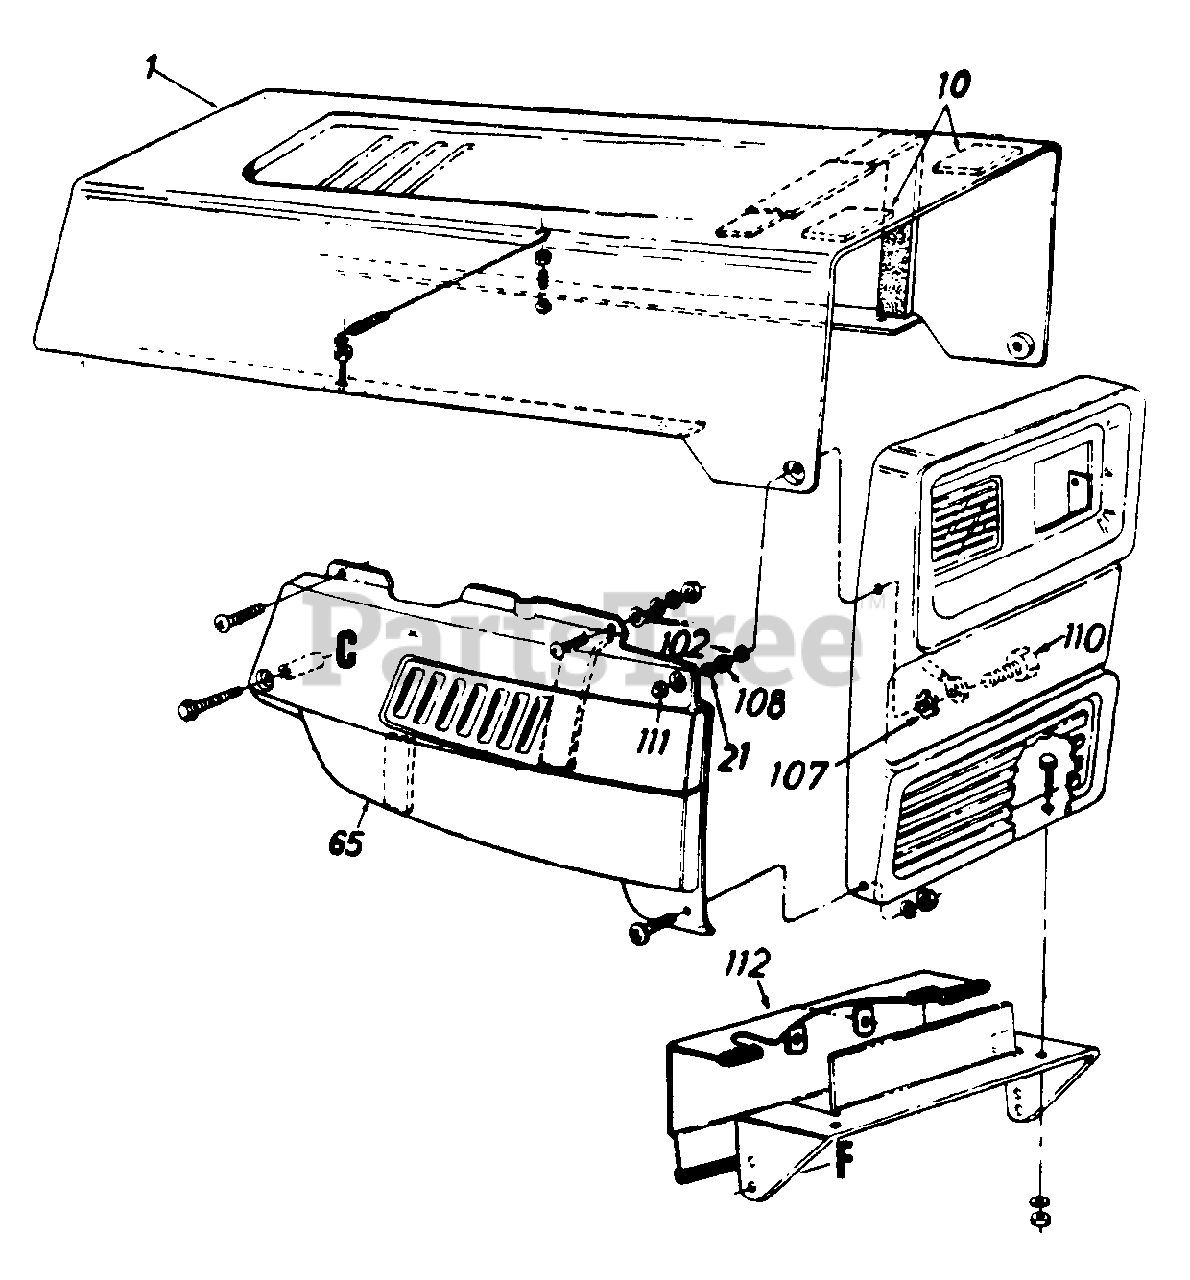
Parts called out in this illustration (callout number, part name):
21	Hex Nut 1/4-20 Thd.
107	Ext. L-Wash. 1/4" I.D.
108	Shld. Spacer
110	Hex Bolt 1/4-20 x .88" Lg.
111	Acorn Nut 1/4-20 Thread
112	Baffle Ass'y. Comp.
